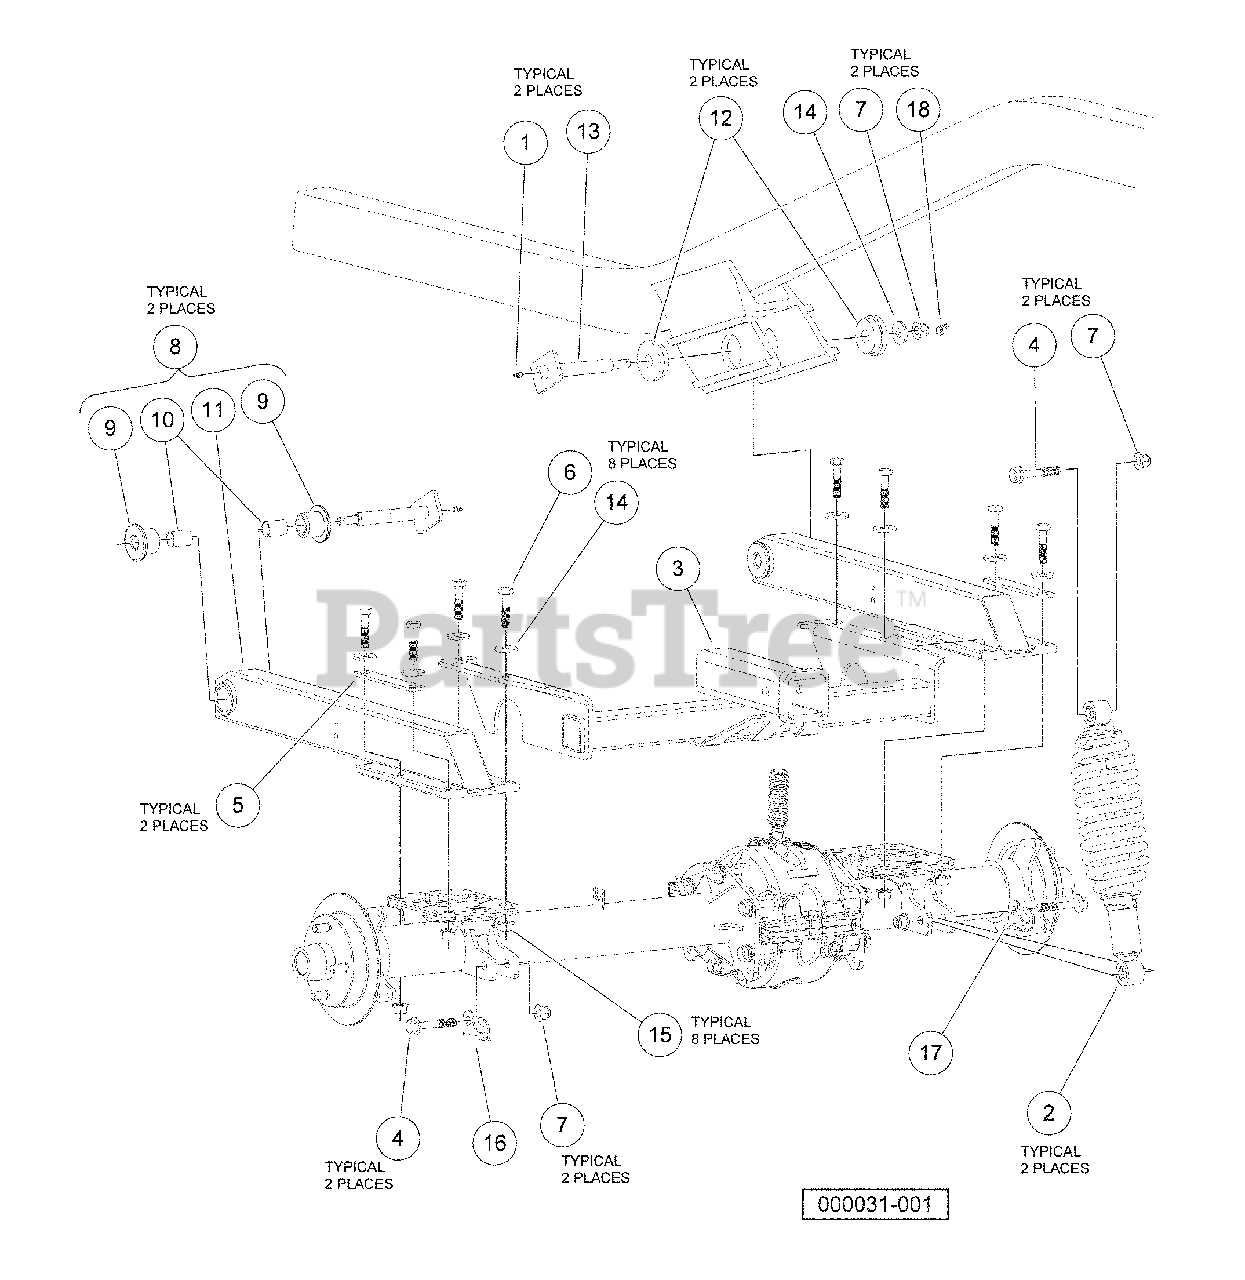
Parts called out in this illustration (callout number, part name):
1	Fitting, 1/4-28 Thread-Forming Grease
2	Shock, Coil Over Rear
3	Weldment, Receiver, Rear
4	Bolt, Flange Head, M12 X 1.75 X 70
5	Washer, Strip, Swingarm
6	Bolt Flanged Head, M12 X 1.75 X 50.
7	Nut Flg, M12x1.75, Nylon Gr 10.
8	Sub Asm Swingarm
9	Bushing, Pivot, Urethane
10	Bushing, Teflon
11	Swingarm, Rear, Awd
12	Insert, Flanged, H-Bracket
13	Pin, Swingarm, Weldment
14	Washer, M12 Hard Regular
15	Nut Flg M12 X 1.75 Cl10
16	Brkt, Line, Hyd, Shk Mnt, Drv.
17	Brkt, Line, Hyd, Shk Mnt, Pass
18	Cotter, Rue Ring, 1/2".
